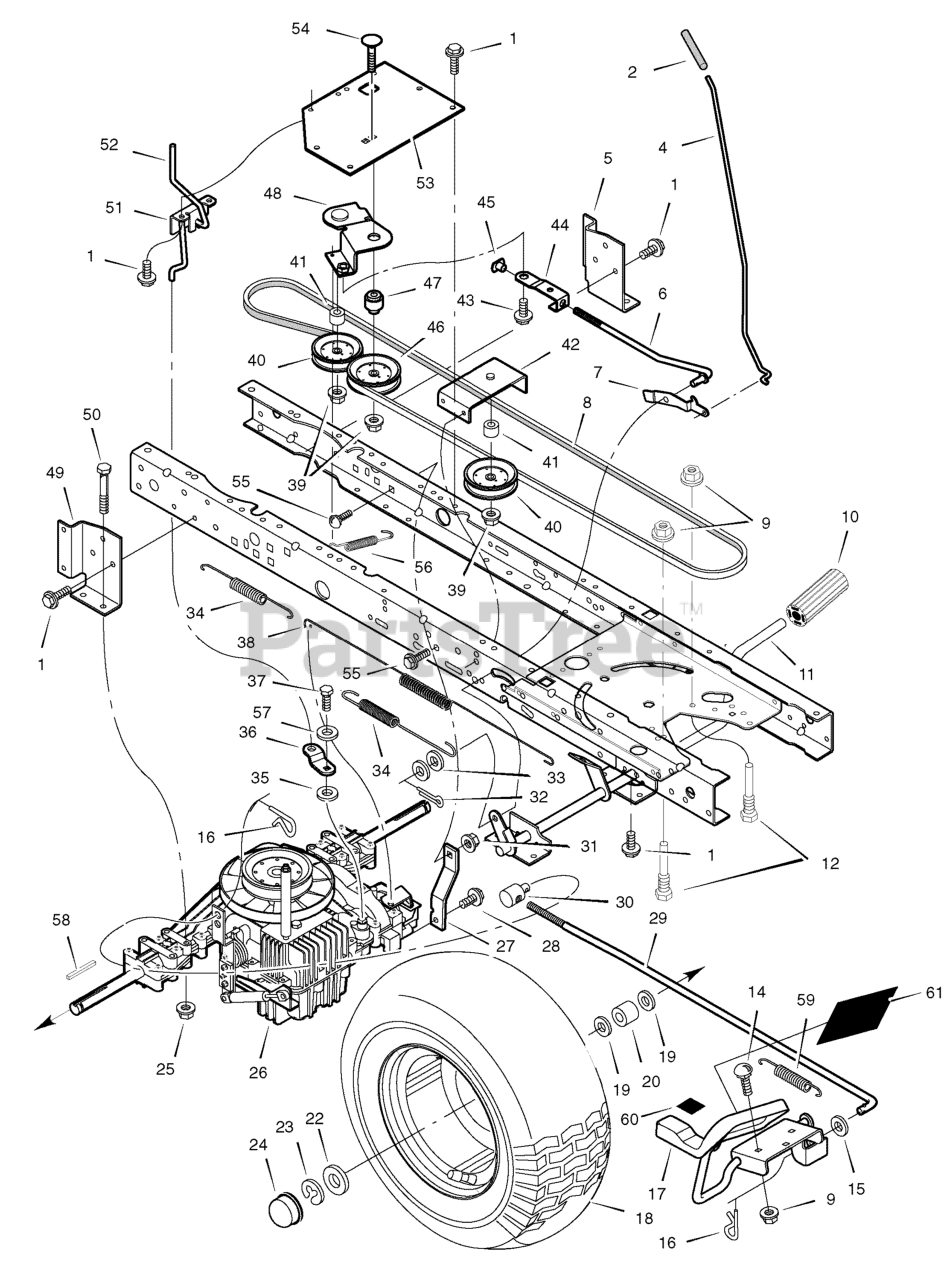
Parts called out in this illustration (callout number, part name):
2	Grip, Parking Brake
4	Rod, Parking Brake
5	Bracket, Left Transaxle
6	Rod, Clutch
7	Latch, Parking Brake
8	V-Belt, Drive
9	Nut, Flange
10	Pedal, Brake/Clutch
11	Assembly, Brake Pedal
12	Screw, Guide
14	Bolt, Carriage
16	Pin, Hair
17	Pedal Assembly, Hydro
18	Wheel & Tire Assembly, Rear
24	Cap, Hub
25	Nut, Centerlock
26	Transaxle, Peerless Hydro **
27	Strap, Torque
29	Rod, Control
30	Nut, Adjusting
31	Nut, Centerlock
32	Pin, Cotter
34	Spring, Extension
36	Arm, Disconnect
37	Capscrew
38	Spring, Brake
39	Locknut, Flange
40	Pulley, Idler
42	Bracket, Idler Assembly
43	Bolt, Shoulder
44	Link, Clutch
45	Nut, Tee
46	Pulley, Idler
47	Bushing, Pivot
48	Arm Assembly, Idler
49	Bracket, Right Transaxle
50	Bolt, Hex
51	Bracket, Dump Valve
52	Rod, Roll Release
53	Bracket, Idler Pivot
54	Bolt, Carriage
55	Bolt, Carriage
56	Spring, Clutch
58	Key, Square 3/16"
59	Spring, Extension
60	Mat, Toe Reverse
61	Pad, Pedal
